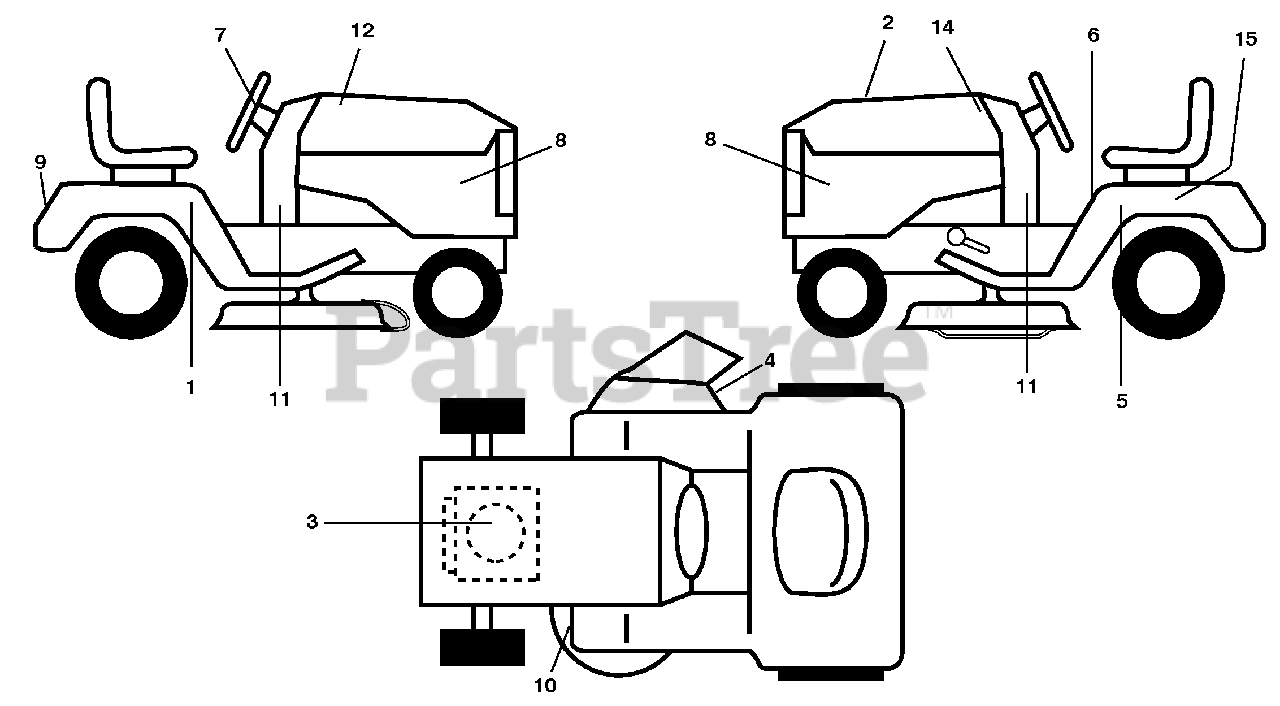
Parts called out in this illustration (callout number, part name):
1	Decal, Fender RH
2	Decal, Replacement
3	Decal, Engine HP
4	Decal, Warning
5	Decal, Fender LH
6	Decal, Fender Danger Eng/Fr
7	Decal, Ins Str Wh
8	Decal, Side Panel
9	Decal, Fender
10	Decal, V-Belt Sch.
11	Decal, Lower Dash
12	Decal, Hood RH
14	Decal, Hood LH
15	Decal, Caution, Battery
15	Decal, Handle Lft Height Adj.
15	Pad Footrest LH
15	Pad Footrest RH
15	Manual, Operator's (E&F)
15	Manual, Parts (E&F)
